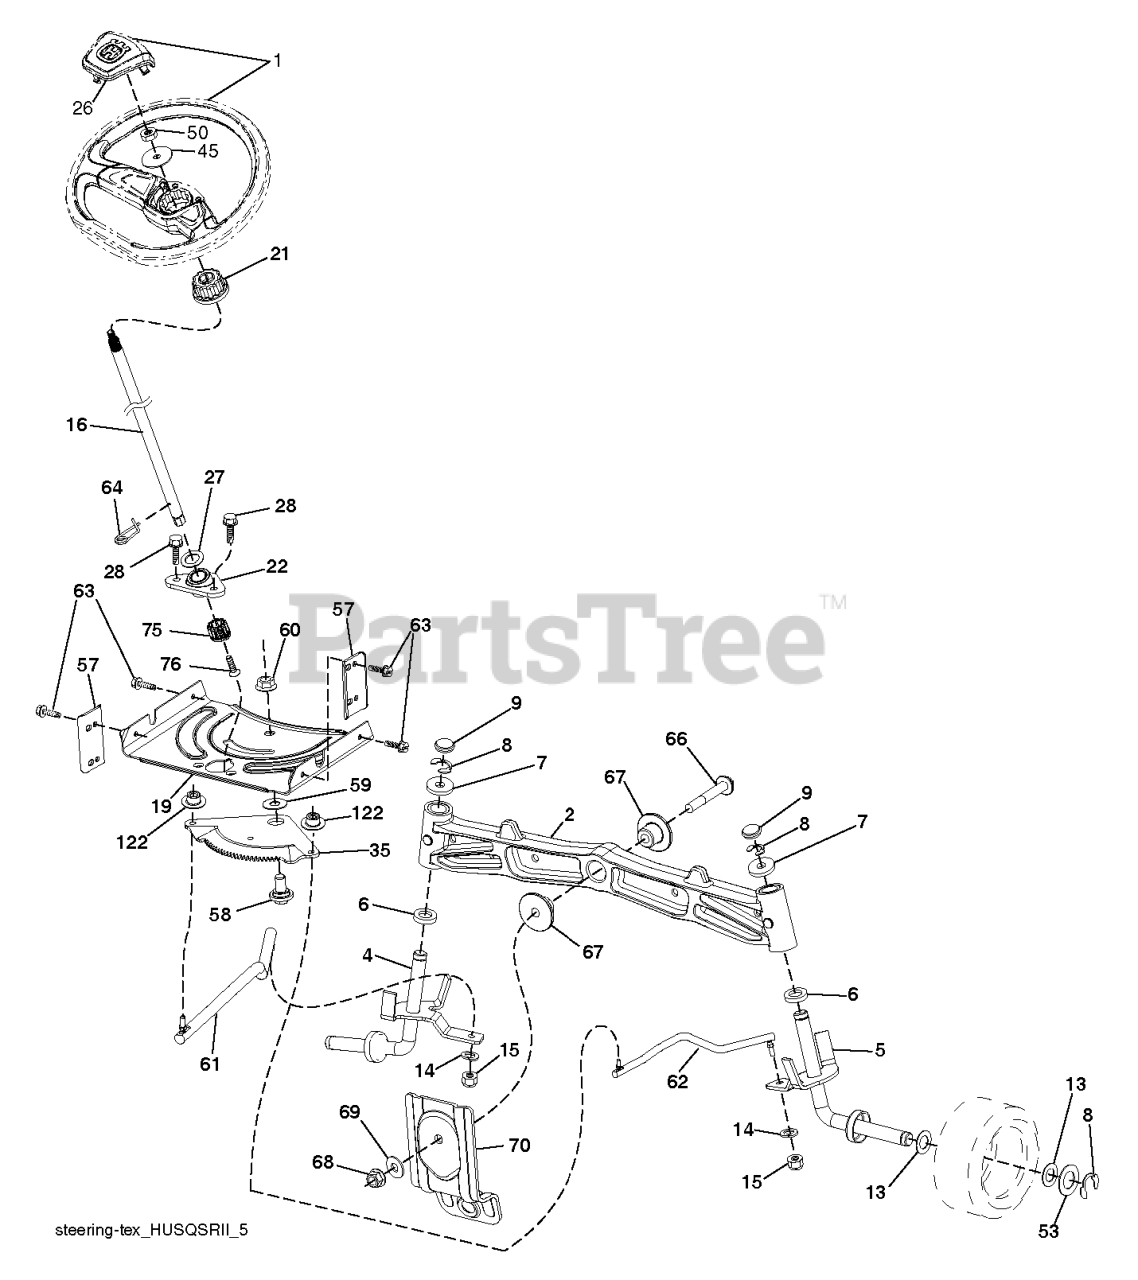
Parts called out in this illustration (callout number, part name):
1	Service Kit
2	AXLE.SVC.ASM CAST IRON.TEX
4	SPINDLE.WLDMT.LH.15INTIRE.X431
5	SPINDLE.WLDMT.RH.15INTIRE.X431
6	WASHER THRUST
9	CAP.SPINDLE.BLACK
15	NUT CROWNLOCK 3/8-24
16	KIT.SRVC.STEERINGSHAFT.2HISHFT
19	SERVICE KIT PLATE PLATE.STEER.
21	KIT.SRVC.STEERINGSHAFT.ADAPTER
22	KIT.SRVC.STEERINGSHAFT.LWRBSHG
28	SCREW, 3/8-16X3/4
35	GEAR.SECTOR.PLATE.DDL.
45	WASHER.3/8ID.2-3/8OD.12GA.PLTD
50	NUT.HEX.FLANGE.3/8-16.LOCKNUT
53	WASHER.HARDENED
57	BRACKET.UPSTOP.TEX
58	BOLT.SHOULDER.SECTOR.P
59	WASHER.THURST.SECTOR.S
60	NUT.FLANGE.LOCK.5/8-11
61	Links
62	Links
63	BOLT.HEX.HD.WASHER.5/16-18X.75
64	RETAINER.CLIP.SPRING.S
66	BOLT HEX FGHD 7/16-14 X 3 SERR
68	NUT.LOCK.FLANGE.7/16
69	WASHER.1.5X.505X.118
70	BRACKET FRONT DECK SUSPENSION
75	KIT.SRVC.STEERINGSHAFT.PINION
76	SCREW HEAD SOCKET LRVB
122	CAP.GEAR.SECTOR.TEX
